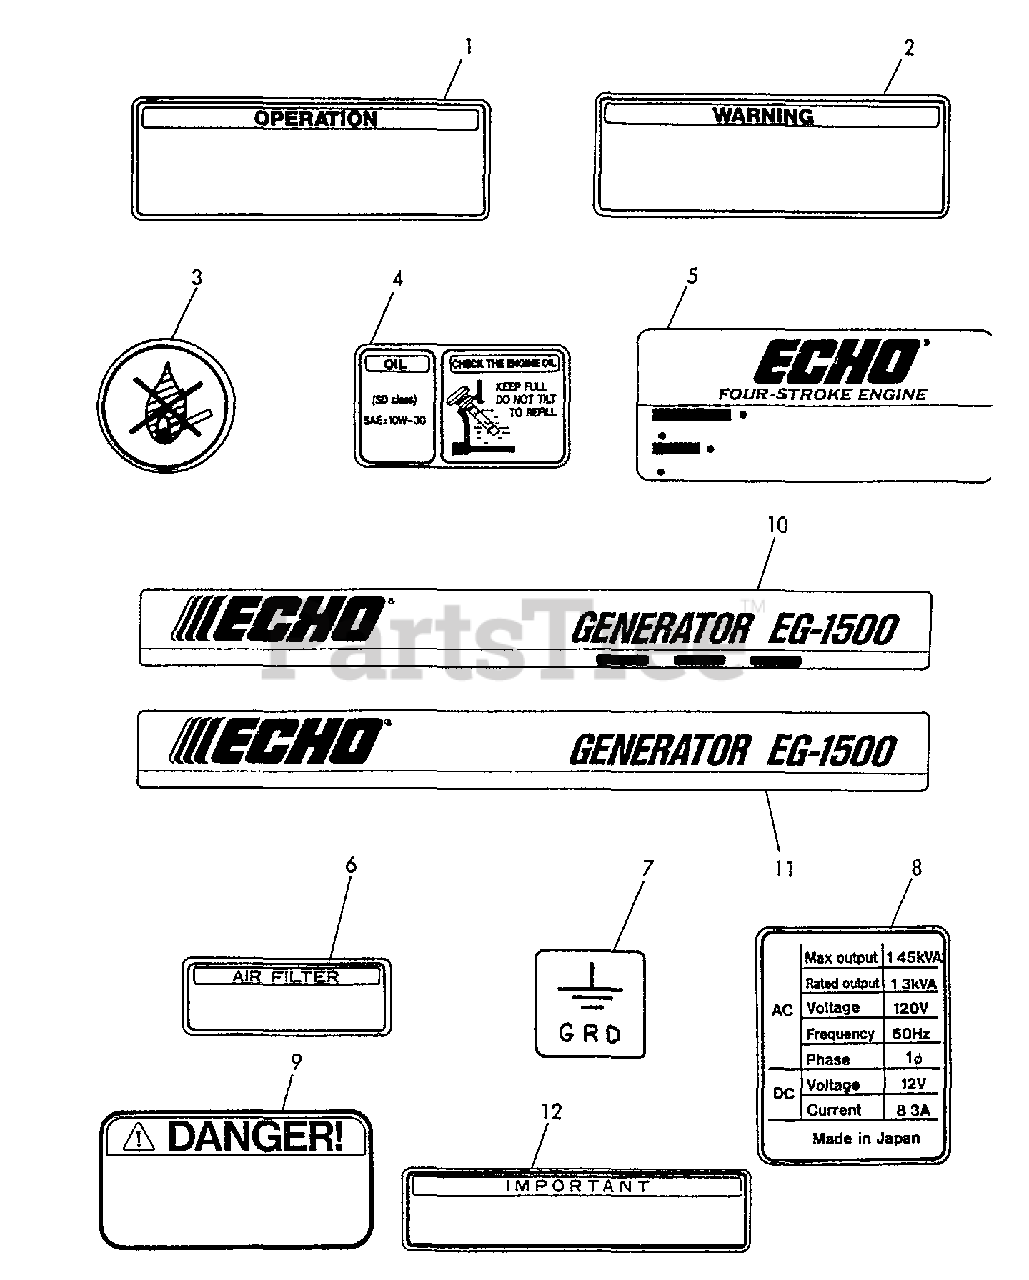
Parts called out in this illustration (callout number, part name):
1	LABEL - OPERATION
2	LABEL - WARNING
3	LABEL - NON FIRE
4	LABEL - OIL
5	LABEL - ECHO
6	LABEL - AIR CLEANER
7	LABEL - GROUND
8	LABEL - GENERATOR
9	LABEL - DANGER
10	LABEL - GENERATOR
11	LABEL - GENERATOR
12	LABEL - IMPORTANT
